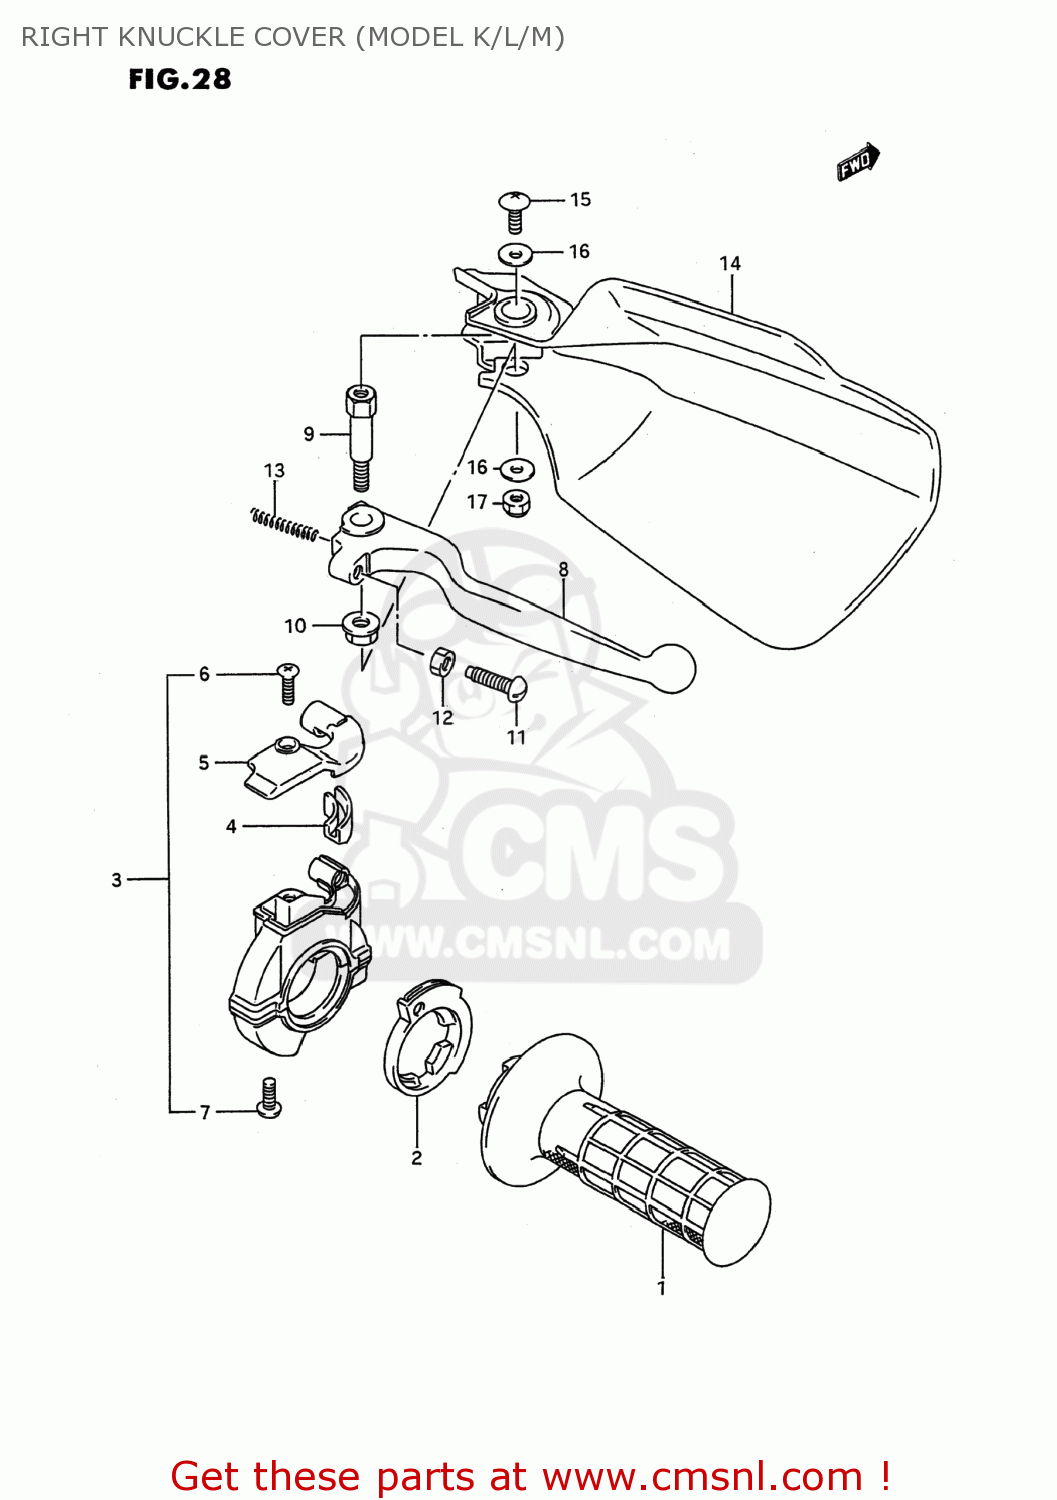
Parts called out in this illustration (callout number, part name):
1	GRIP,THROTTLE
2	ROTOR,THROTTLE GRIP
3	CASE ASSY,THROTTLE
4	GUIDE PIECE,THROTTLE
5	COVER,THROTTLE CASE
6	SCREW 4X10
7	SCREW
8	LEVER,BRAKE
9	BOLT,BRAKE LEVER PIVOT
10	NUT 6MM
11	BOLT,ADJUST
12	NUT ,5MM
13	SPRING,RETURN
14	COVER,KNUCKLE,R
15	SCREW(5X10)
16	WASHER (5.5X16X1.2)
17	NUT 6MM
